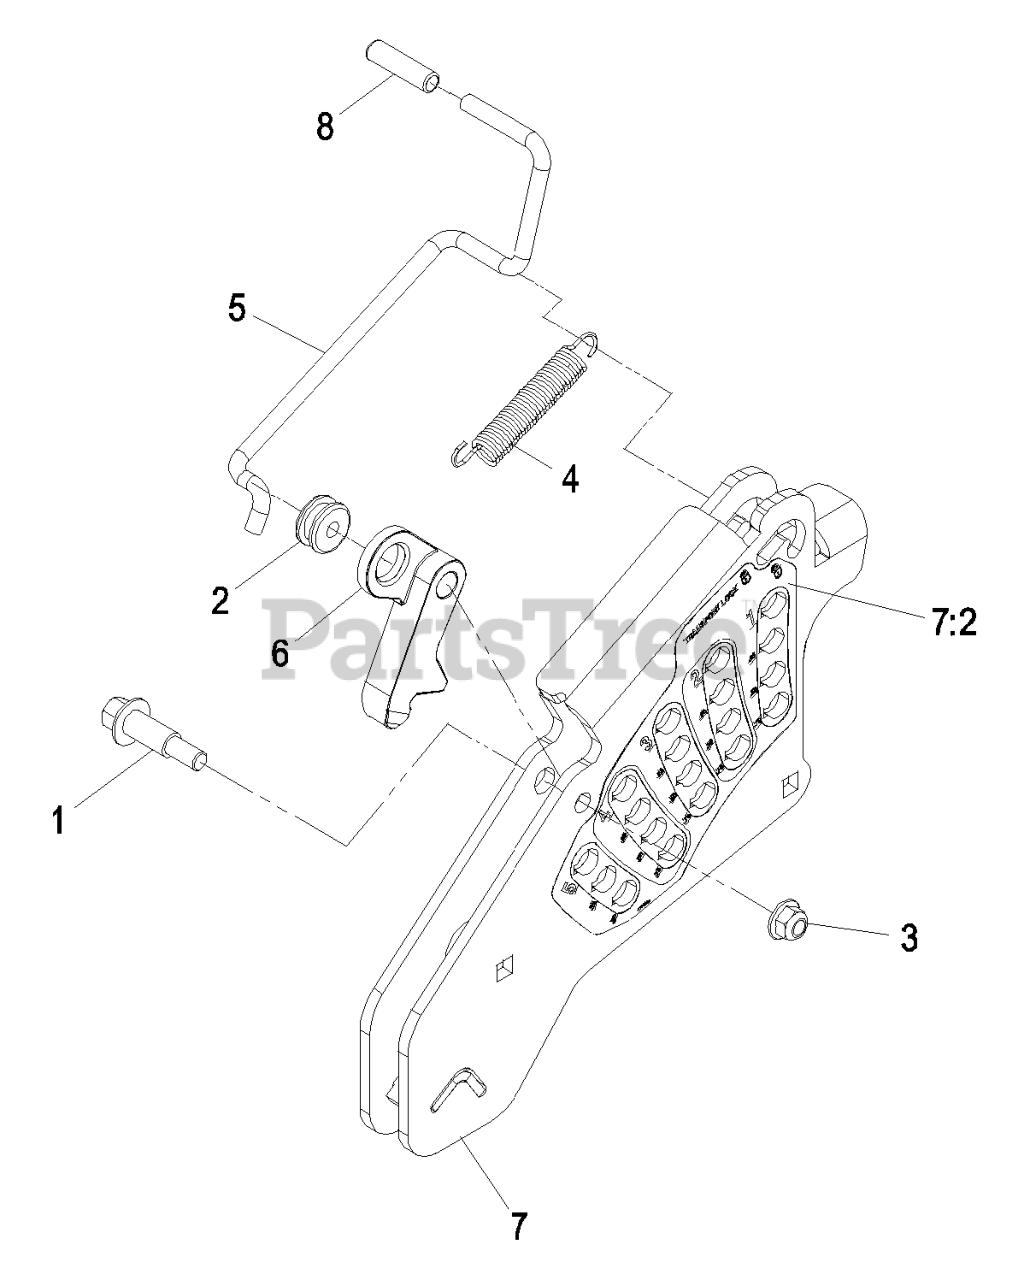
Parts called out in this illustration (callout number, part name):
1	BOLT-SHOULDER
2	GROMMET
3	NUT-HF, NI
4	SPRING-EXTENSION
5	ROD-LOCK, TRANSPORT
6	PAWL-TRANSPORT, HOC
7	HOC PLATE ASM
7:2	DECAL-HOC
8	GRIP-LEVER
